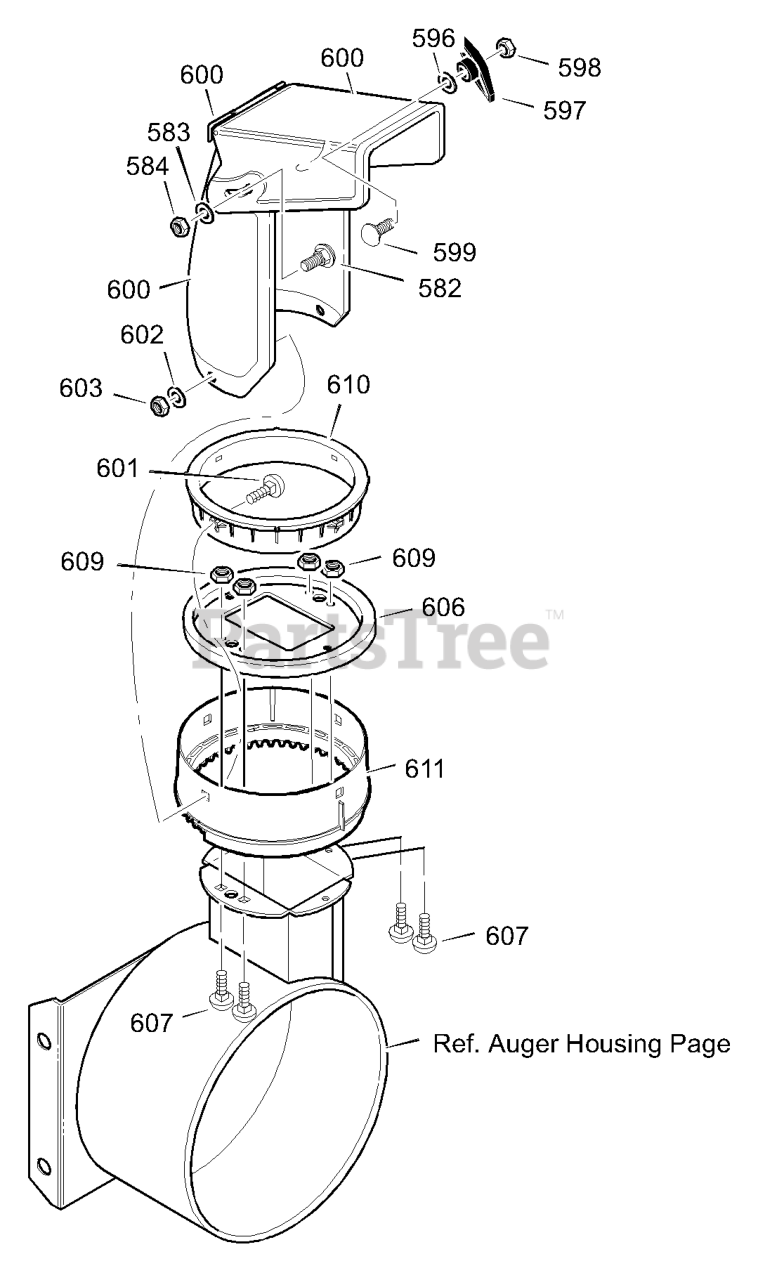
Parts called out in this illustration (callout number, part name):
582	SCREW, 5/16-18 x 1.00
583	WASHER, FLAT
584	NUT, 5/16-18
596	WASHER
597	KNOB, T 3.00
598	NUT, 5/16-18
599	BOLT, 5/16-18X1..00
600	CHUTE ASSEMBLY
601	BOLT, 5/16-18
602	WASHER, FLAT
603	NUT, 5/16-18
606	CHUTE COLLAR
607	SCREW, 1/4-20 X 0.75
609	NUT, 1/4-20 HEX NYLOCK
610	RETAINER RING INNER
611	RETAINER RING OUTER
870	CRANK, ASSY CHUTE
